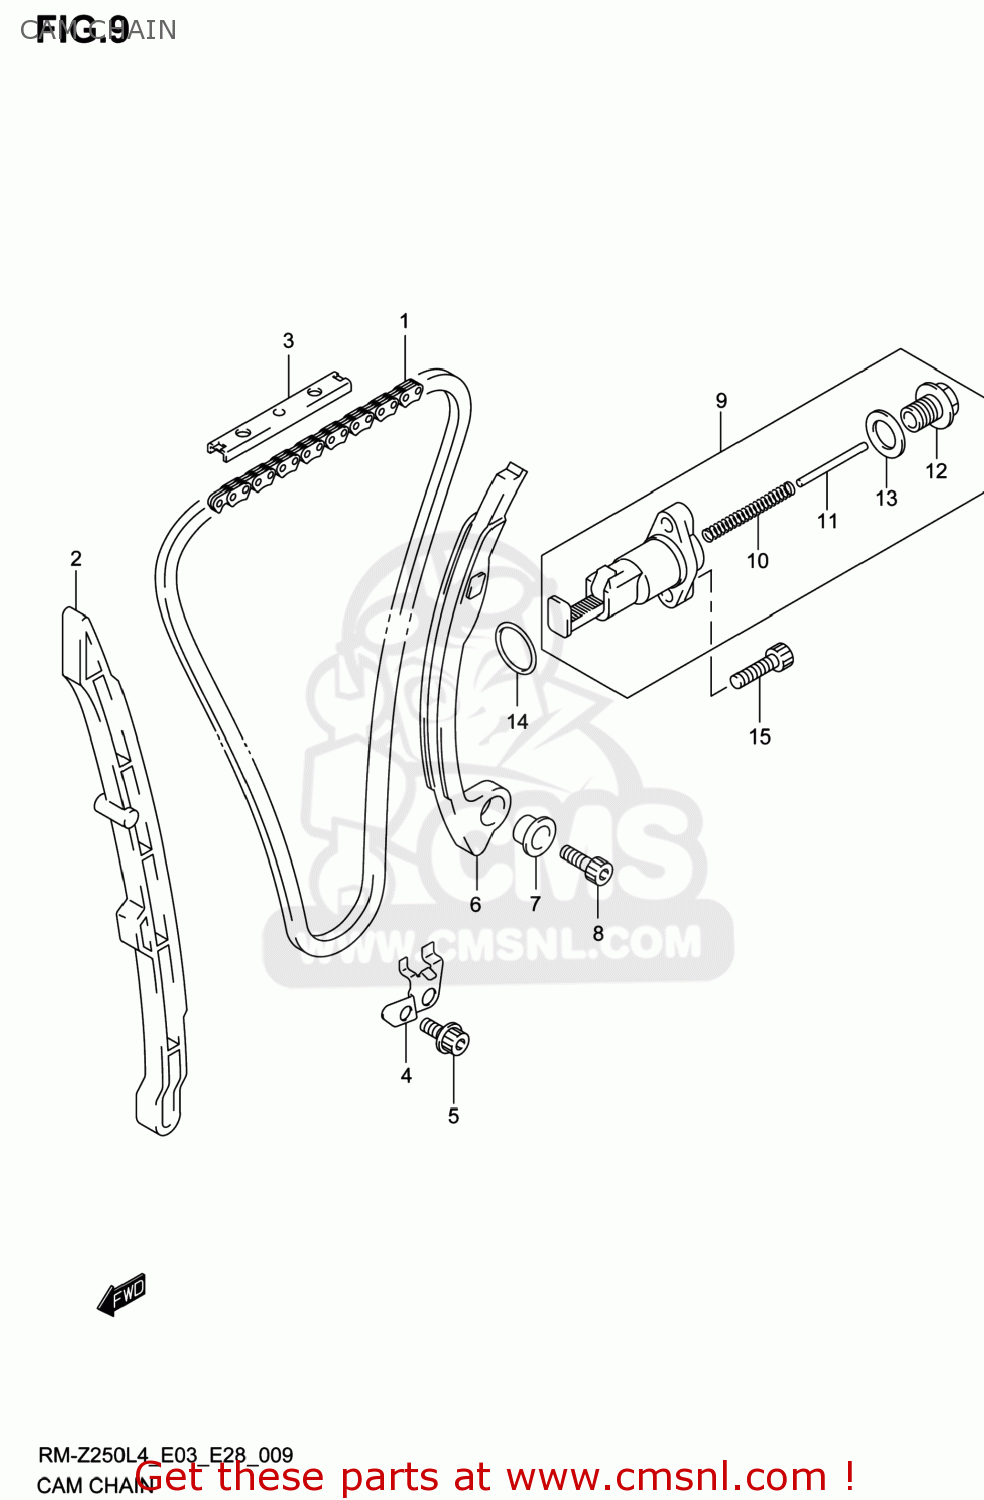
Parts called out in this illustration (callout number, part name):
1	CHAIN,CAMSHAFT DRIVE
2	GUIDE,CAM CHAIN NO.1
3	GUIDE,CAM CHAIN NO.2
4	RETAINER,CAM CHAIN GUIDE NO.1
5	BOLT
6	TENSIONER,CAM CHAIN
7	SPACER,CAM CHAIN TENSIONER
8	BOLT
9	ADJUSTER ASSY,TENSIONER
10	SPRING,ADJUSTER
11	BAR,ADJUSTER
12	PLUG,ADJUSTER
13	GASKET,TENSIONER ADJUSTER (NAS)
14	O RING(D:1.9,ID:18.8)
15	BOLT
